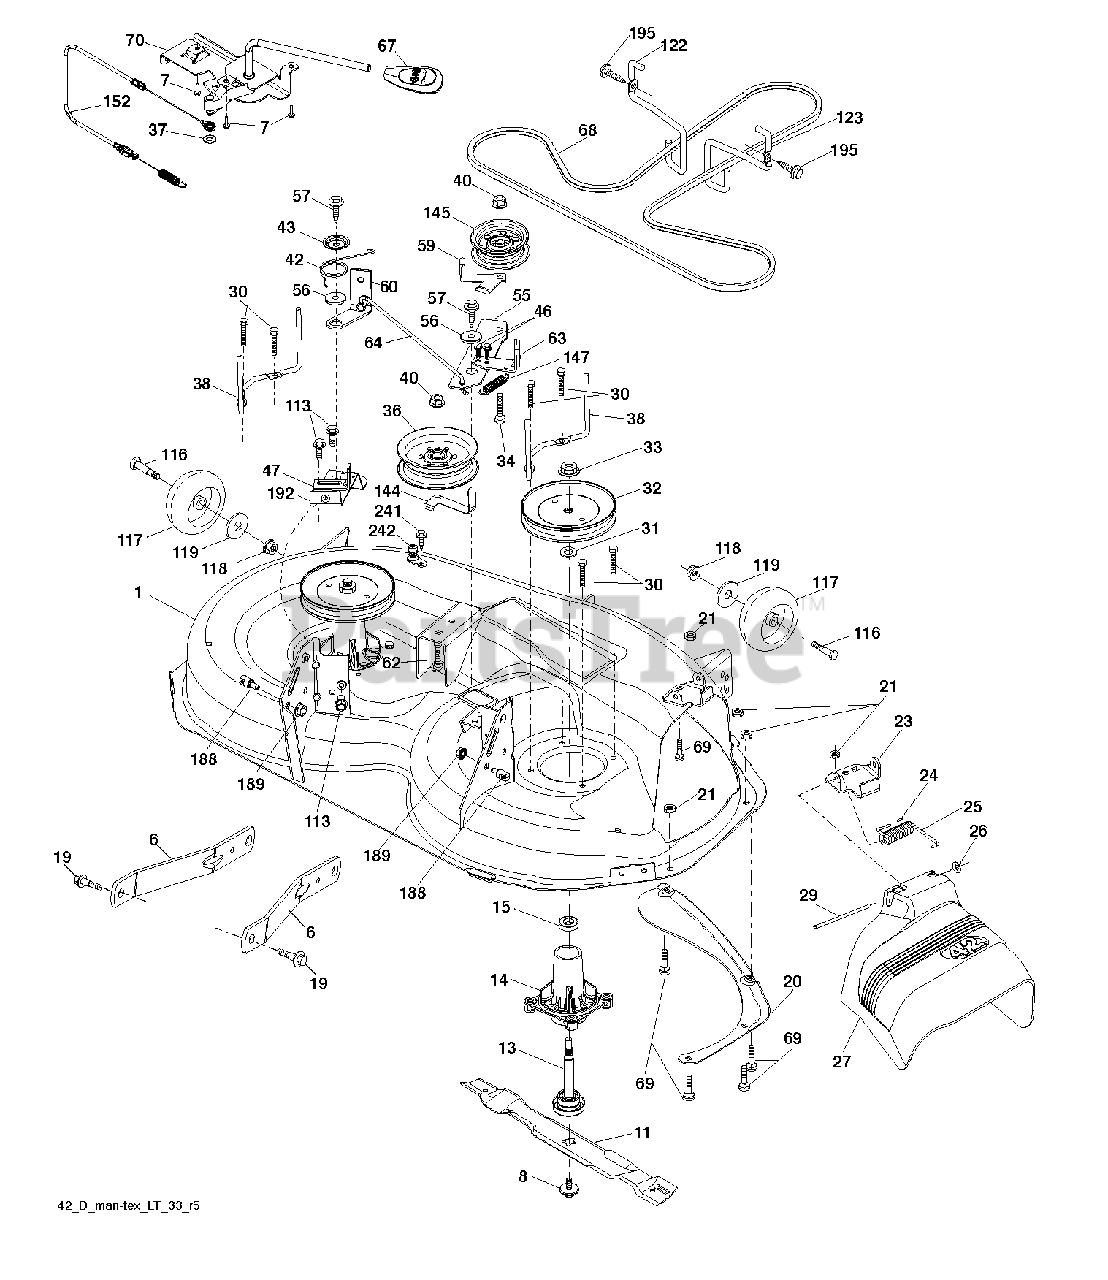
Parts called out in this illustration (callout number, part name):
1	DECK.WELDMENT.42"
6	ARM.SUSPENSION.MOWER.R
7	SCREW.#10 X 0.750.BOS THREAD
8	BOLT.WASHER.ASM.7/16-2
11	42" HI-LIFT BLADE
13	SHAFT.ASM.MDRL.N/GREASE.38
14	HOUSING MANDREL
19	BOLT.SHOULDER
20	BAFFLE.VORTEX
21	LOCKNUT
23	BRKT.DEFLECTOR.38"2005+
24	CAP-SLEEVE LT
25	SPRING.TORSION.DEFLECT
27	SHIELD.DEFLECTOR.MOWER.42"BLAC
29	ROD.HINGE
30	SCREW, WASHER HEAD
31	WASHER.SPACER.MANDREL
32	PULLEY.MANDREL.5.438.PD
33	NUT.FLANGE.LOCK.TOP
34	BOLT.3/8-16X1.50
36	PULLEY.IDLER.2006
38	KEEPER.BELT.MANDREL.PULLEY
40	NUT LOCK FLG 3/8-16 UNC
42	SPRING.TORSION.BRAKE
43	SRPING.TORSION.RETAINE
46	SCREW.1/4-20X5/8
47	BRKT.CLUTCH.CABLE
55	IDLER.ARM.42"
56	SPACER.RETAINER
57	SCREW 3/8-16X1
60	ARM BRAKE MOWER
62	BOLT
63	ARM BRAKE MOWER
64	LINK BRAKE
68	V BELT
69	BOLT
70	CLUTCH.ASM.MANUAL.LT.PRED
113	BOLT.5/16HEX.WHS.HD
116	Shield Bolt, A 2.41 B 1.66
117	WHEEL.GAGE.HALF.SPOKED
118	LOCKNUT
119	WASHER
122	KEEPER BELT ENGINE LH
123	KEEPER BELT RH
144	KEEPER.BELT.MOWER
145	PULLEY.IDLER.48"PRIMARY
147	RETURN SPRING
152	CABLE.CLUTCH.MANUAL.
188	STUD.FASTNER.W/ANTI-ROTATE
189	NUT LOCK HEX FLANGE 5/16-18
192	BRKT.BRAKE.STAND.LH.
195	SCREW, 3/8-16X3/4
198	BAFFLE CENTER FRONT
199	BAFFLE FRONT RH
200	WASHER.13/32 X 1 X 1/2.11GUARD
